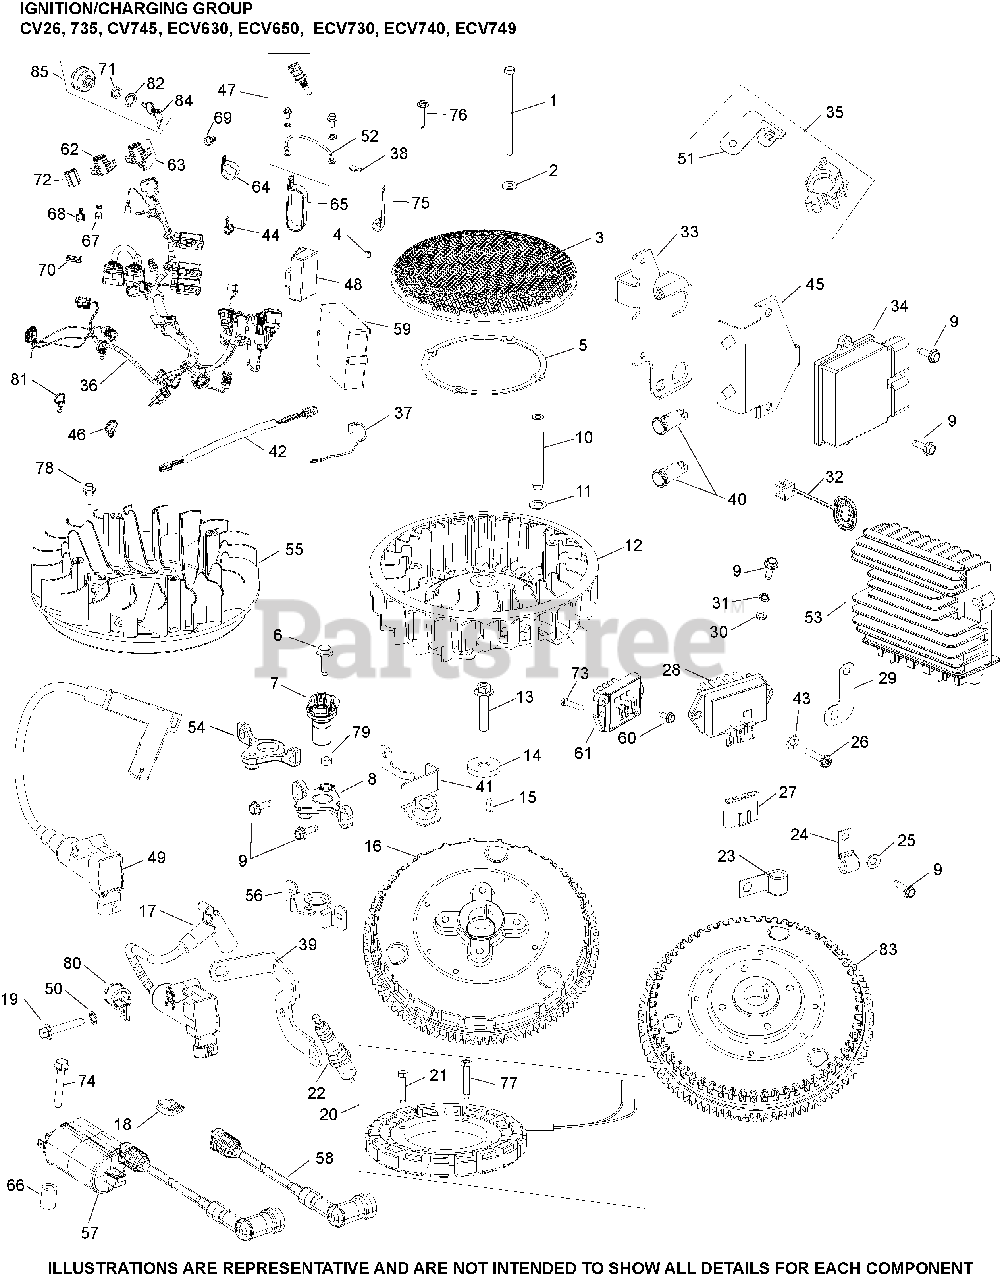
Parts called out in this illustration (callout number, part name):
1	SCREW, CAP M6X1.0X99.5
2	WASHER, FLAT 1/4" (O.D. 5/8")
3	SCREEN, GRASS
4	SCREW, SKT SET #10-24X1/4"
5	RING, SUPPORT
6	SCREW, THREAD FORMING
7	SENSOR, SPEED
8	BRACKET, SENSOR SPEED
9	SCREW, THREAD FORMING
11	WASHER, SPRING 10 MM
13	SCREW, FLG M10X1.5X45 - (#25086361S)
14	WASHER, FLAT 13/32"
15	KEY, 3/16" X 5/8"
16	FLYWHEEL ASSEMBLY
17	COIL, IGNITION - EFI
18	NUT, PLASTIC
18	CLIP, SNAP-IN
19	SCREW, FLG M6X1.0X34
20	KIT, 15 / 20 AMP STATOR
21	SCREW, THREAD FORMING
22	SPARK PLUG, RFI
25	WASHER, FLAT 1/4" (O.D. 1/2")
26	SCREW, HEX FLANGE HI-LO
27	CONNECTOR
31	WASHER, INT TOOTH LOCK #10
32	CAP, CONNECTOR
33	BRACKET, ECU
34	MODULE, ECU ECV650 USE 24 584 185-S
35	KIT, MOUNTING CLIP
36	HARNESS, WIRING ASSEMBLY
50	WASHER, INT TOOTH LOCK 1/4"
51	CLIP, MOUNTING BRACKET USE 25 154 21-S
60	SCREW, THREAD FORMING
61	REGULATOR, RECTIFIER (20-30AMP,FW W/O USE 25 403 39-S
65	CLAMP, INSULATED DOUBLE
